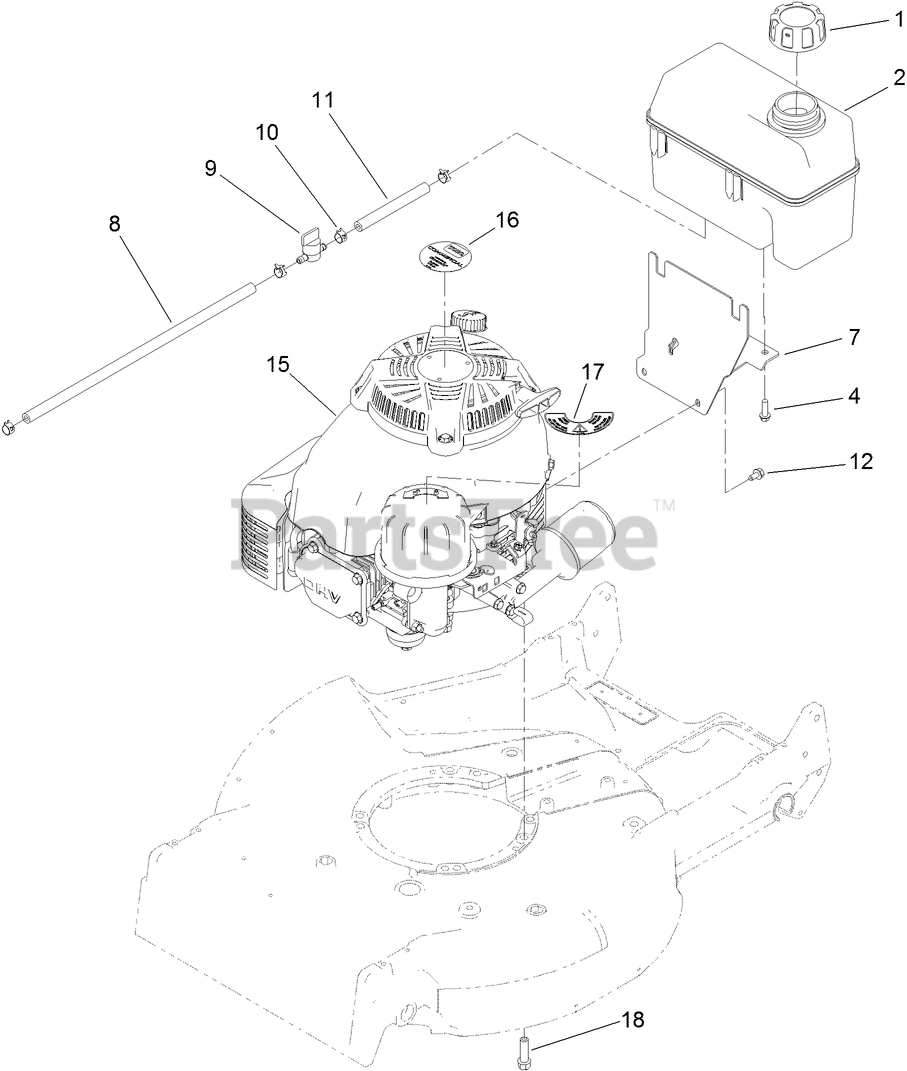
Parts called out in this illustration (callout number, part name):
1	CAP-GAS
2	TANK-FUEL
4	SCREW-HWH
7	MOUNT-TANK
8	HOSE-FUEL
9	VALVE-FUEL
10	CLAMP-HOSE
11	HOSE-FUEL
12	SCREW-HWH
15	ENGINE-KAWASAKI, FJ180V-BM07-M GAS
18	SCREW-TAPTITE
